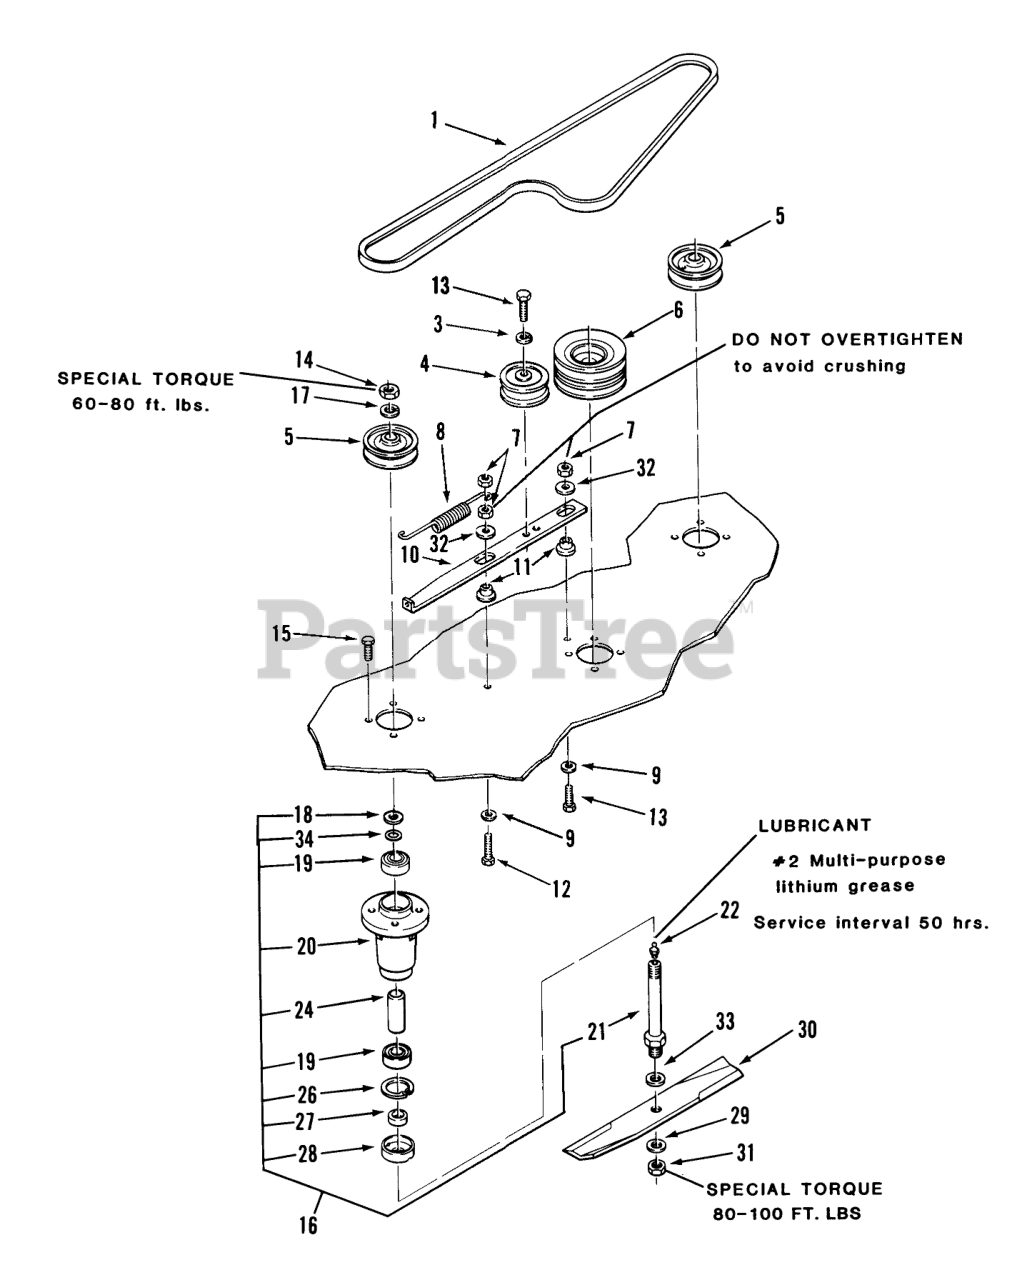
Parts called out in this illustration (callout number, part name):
1	V-BELT
3	WASHER-LOCK
4	PULLEY-IDLER
5	PULLEY
6	PULLEY CENTER
7	NUT-LOCK, NI
8	SPRING-EXTENSION
9	WASHER
10	BAR-IDLER SUPPORT
11	SPACER-BUSHING
12	SCREW-HH
13	SCREW-HH
14	NUT-JAM
15	Bolt
16	Spindle Assembly (Incl. Ref. #18-21, 24, 28, & 34)
17	WASHER-LOCK
18	Washer
19	BEARING-BALL
20	HOUSING-SPINDLE
21	SHAFT-SPINDLE
22	FITTING-GREASE
26	RING-RETAINING
27	SPACER-BLADE
28	CUP-SPINDLE
29	WASHER-FLAT
30	Blade Center
31	NUT-JAM
32	WASHER
33	Washer
34	O RING
